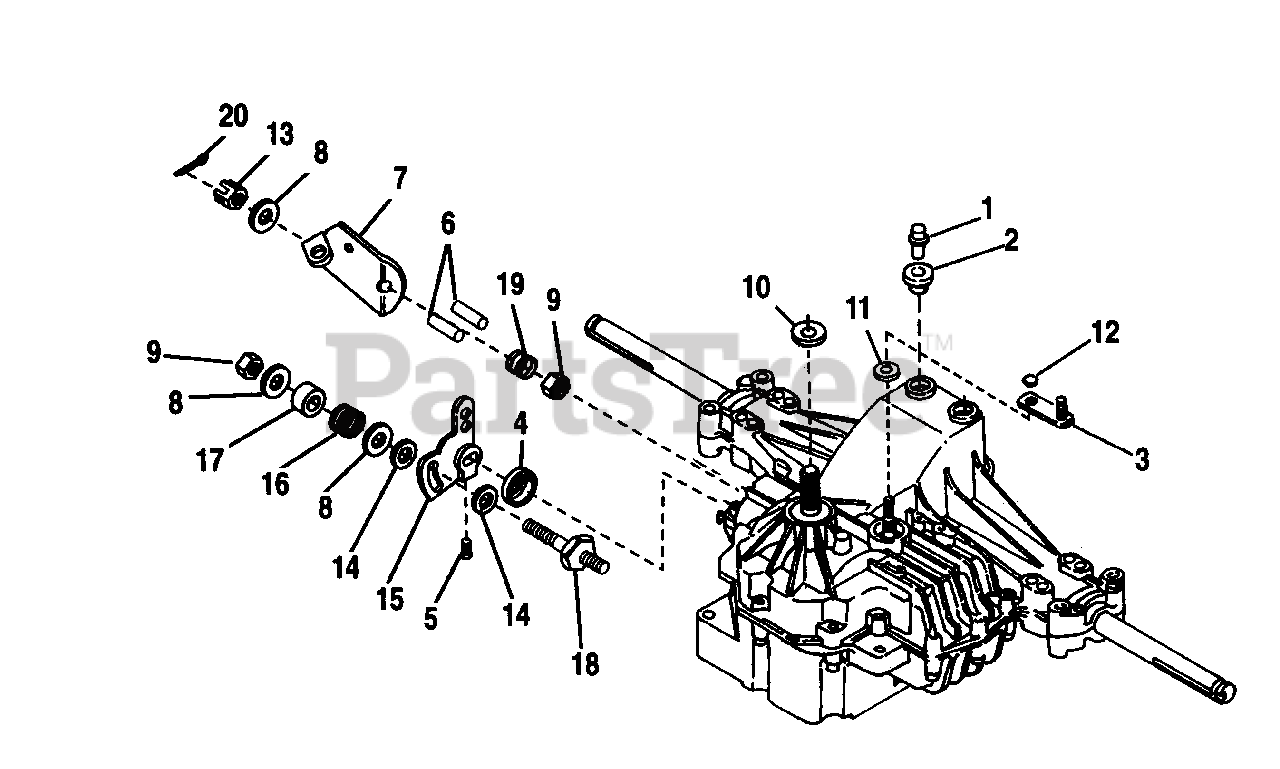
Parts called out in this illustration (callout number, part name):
1	* BREATHER ASSY.
2	* BUSHING, Rubber
3	* ARM, Bypass
5	* SET SCREW
6	* ACTUATOR PIN
7	* ARM, Brake
8	* WASHER, 7/16 x 7/8 x 1/16
9	* NUT, Hex, Lock, 5/16 x 24
10	* SEAL, Lip
11	* SEAL, Lip
12	* RING, Retaining
13	* CASTLE NUT, 5/16-24
14	* PUCK, Dampener
15	* ARM, Control
18	* STUD, 5/16-24
19	* SPRING, Helical Compression
20	* COTTER PIN
